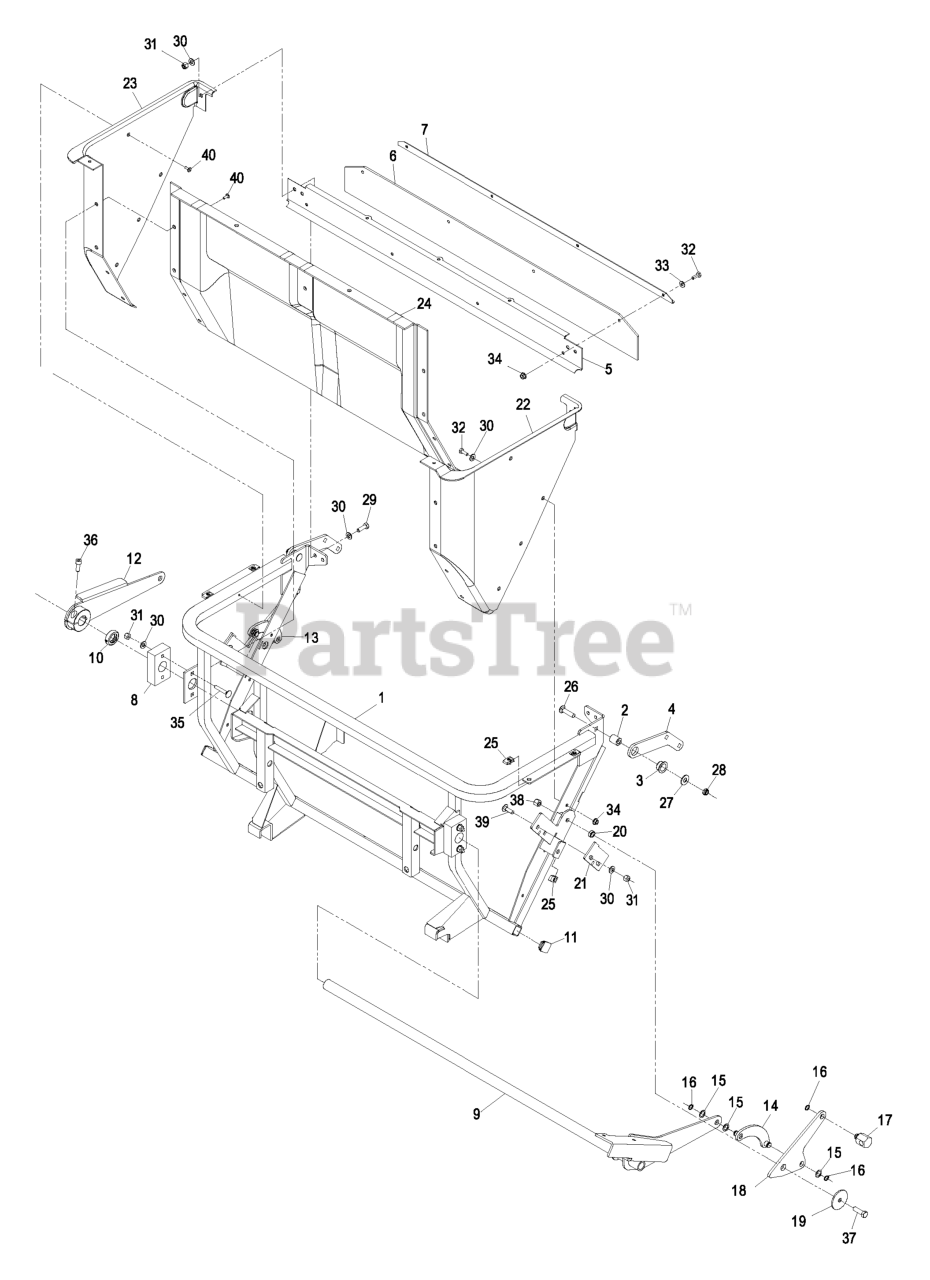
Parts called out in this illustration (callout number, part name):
1	WLD,QDS FRAME
2	PIN-PIVOT, HINGE
3	BEARING
4	PLATE-HINGE
5	PLATE-REAR
6	SEAL-DOOR
7	STRAP-HOLD DOWN
8	BEARING
9	BELLCRANK
10	SHAFT-COLLAR
12	Wld, Link Rh
13	LINK-RH
14	LINK-LH
15	WASHER-NYLON
16	RING-RETAINING
17	TRUNNION-LINK
18	ARM-LINKAGE, DOOR
20	BEARING-LINKAGE, PIVOT
21	STOP-LINKAGE
22	PANEL-BAGGER, LH
23	PANEL-BAGGER, RH
24	PANEL-BAGGER
25	Nut, Retainer 1/4-20
26	SCREW-CARR
27	WASHER-FLAT
29	SCREW-HH
30	WASHER-PLAIN
31	NUT-LOCK, NI
32	SCREW-HH
33	WASHER-FLAT
35	BOLT-CAR
36	SCREW-HSH
37	SCREW-HH
38	NUT-LOCK, NI
39	BOLT-CARR
40	RIVET-BLIND
